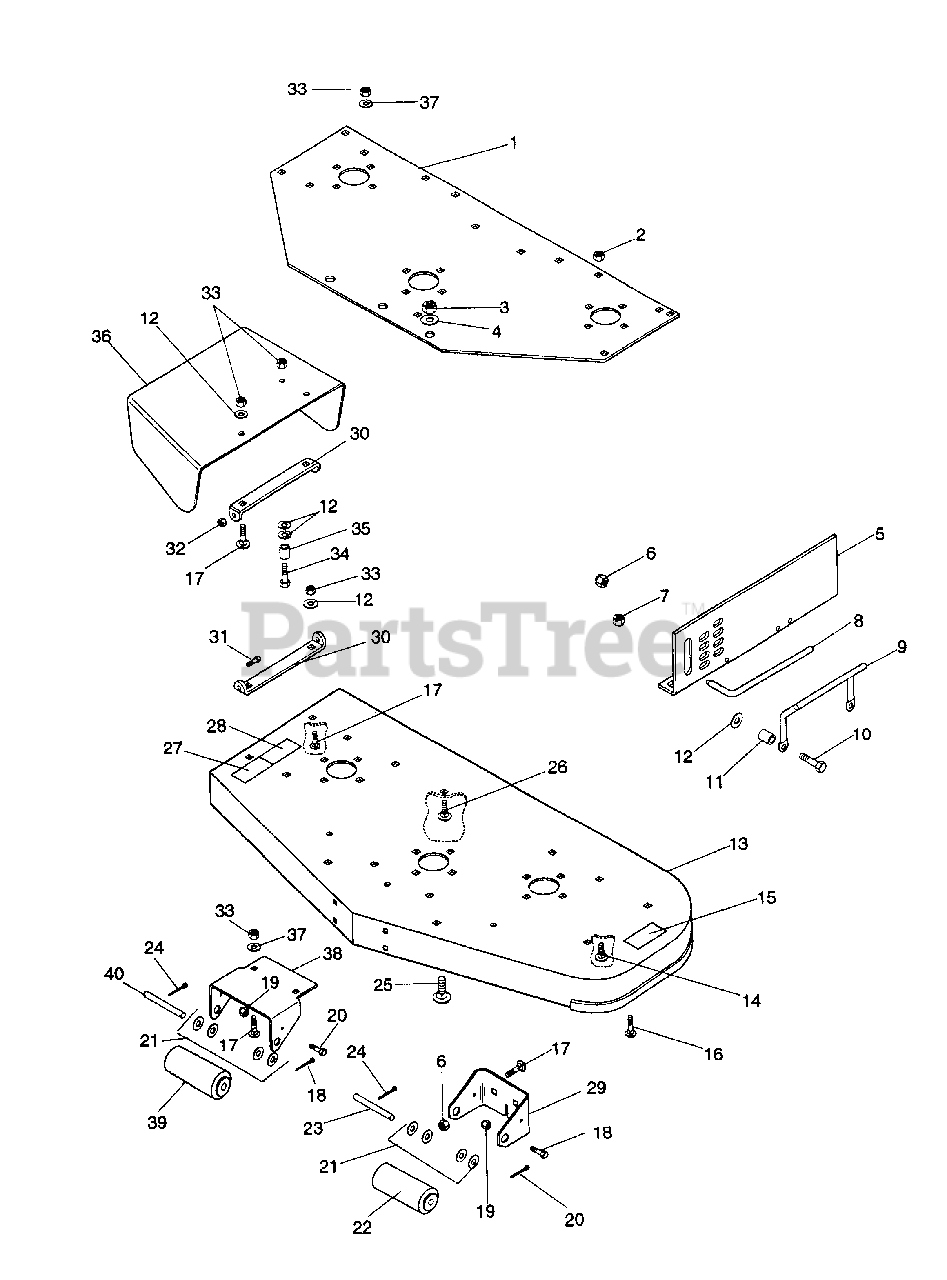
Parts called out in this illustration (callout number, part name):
1	Plate, Support
2	Nut-Lock-Nylon .312-18 Pl
3	Nut-Lock-Nylon .50-13 Pl
4	Washer-Flat-Steel .531 x 1.250 x .100
5	Bracket, Mower Side Support L.H.
5	Bracket, mower Side Support R.H.
6	Nut-Lock-Nylon .375-16 Pl
7	Nut-Lock-Nylon .312-18 Pl
8	Pin, Mower Locking
9	Handle
10	Bolt-Hex .38-16 x 1.75 Pl Gr. 5
11	Bushing
12	Washer-flat-Steel .406 x .812 x .065 Pl
13	Weldment, 50" Mower Fabricated
14	Bolt-Carriage 5/16-18 x .625
15	Decal, Danger Foot
16	Bolt-Carriage 5/16-18 x 1.0
17	Bolt-Carriage .38-16 x 1.0 Pl
18	Bolt-Hex .25-20 x .75 Pl Gr. 5
19	Nut-lock-Nylon .25-20 Pl
20	Pin-Cotter .250 x 2.00
21	Washer-Flat-Steel .656 x 1.312 x .095 Pl
22	Roller, Gage
23	Rod
24	Pin-Cotter .25 x 1.00
25	Bolt-Carriage .50-13 x 1.00
26	Bolt-Carriage 3/8-16 x .75
27	Decal, Warning Eye
28	Decal, Danger Hand
29	Bracket, Roller
30	Bracket, Chute
31	Bolt-Hex .25-20 x .875
32	Nut-Lock-Nylon .250-20 Pl
33	Nut-Lock-Nylon .375-16 Pl
34	Bolt-Hex.38-16 x 1.50 Pl Gr. 5
35	Bushing-Sleave .407 x .625 x .750 Pl
36	Sheild, Safety Extension 50" Mower
37	Wahser-Flat-Streel .406 x .812 x .065
38	Bracket, Gage Roller
39	Roller, Gage
40	Shaft, Center Roller
